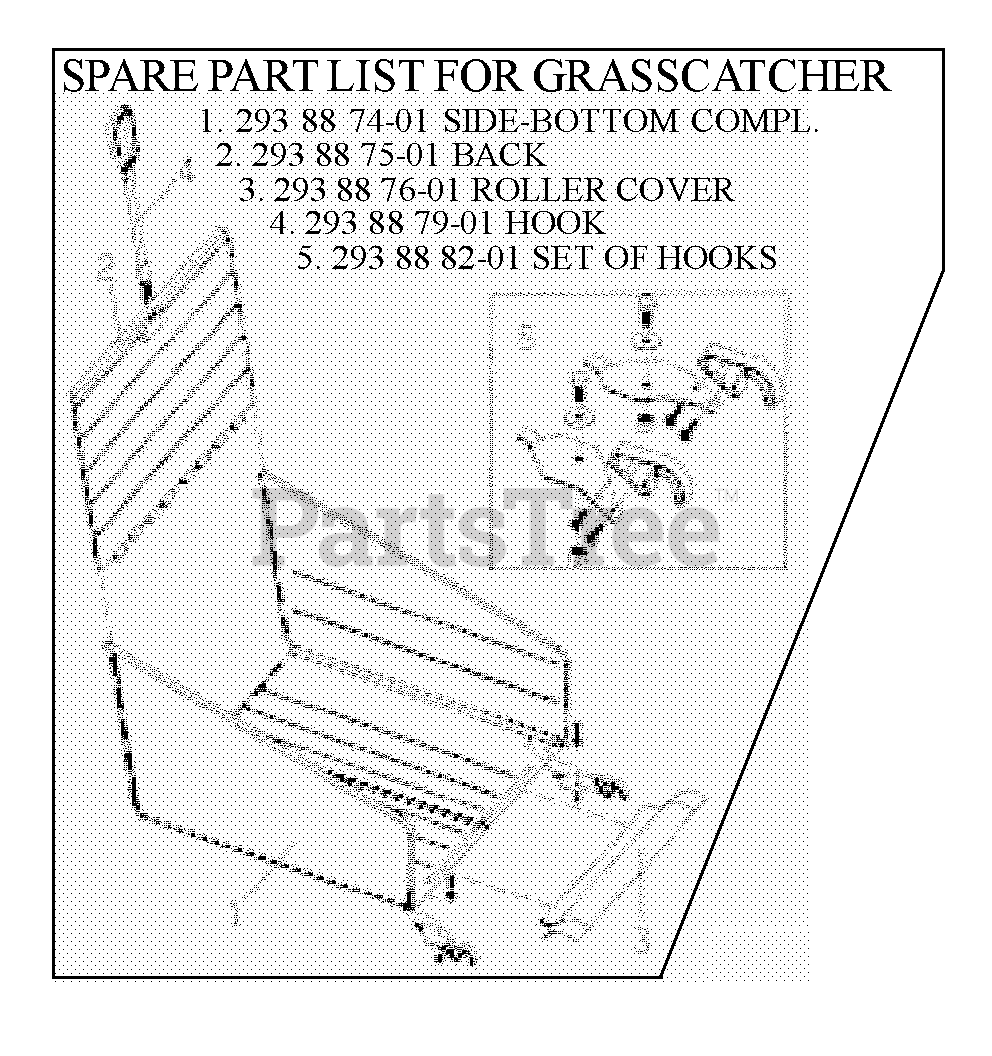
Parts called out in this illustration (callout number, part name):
1	SIDE-BOTTOM COMPL.
2	BACK
3	ROLLER COVER
5	SET OF HOOKS
